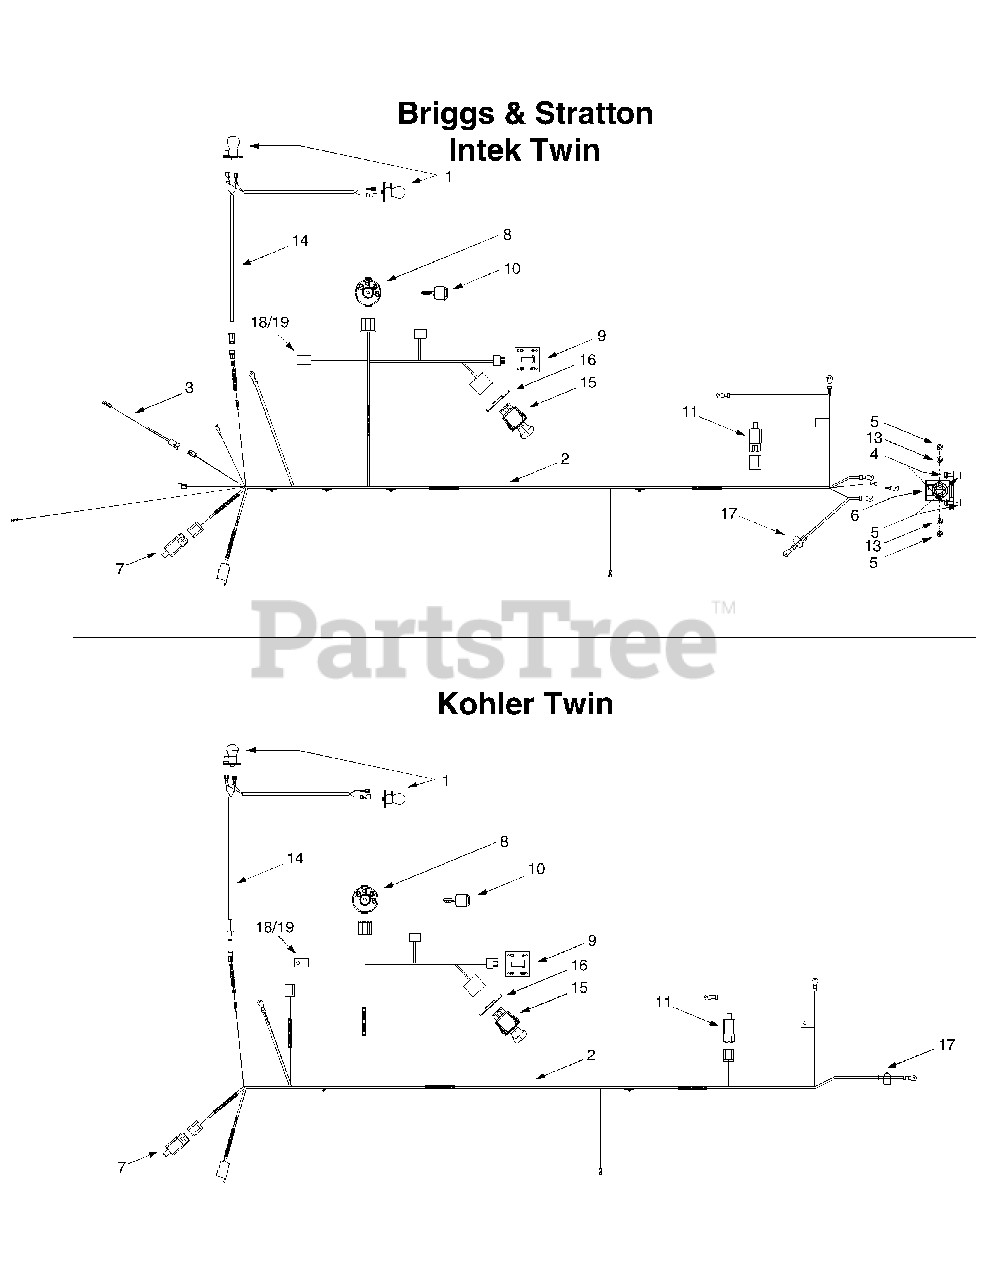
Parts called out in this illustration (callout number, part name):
1	Bulb/Socket Headlight Assembly
2	Wiring Harness w/o Ref. 14 (units w/ B&S Intek Twin)
2	Wiring Harness w/o Ref. 14 (units w/ Kohler Twin)
3	Harness Adapter, #18 x 5
4	Self Tapping Screw, 1/4-20 x .5
5	Hex Nut, 1/4-20
6	Solenoid, 12-volt, 100 Amp
7	Snap Mount Safety Interlock Switch (Brake)
8	Ignition Switch
9	Indicator Monitor / Hour Meter
10	Ignition Key
11	Safety Plunger Switch (Seat)
12	External Lock Washer, 1/4
13	Lock Washer, 1/4
14	Headlight Harness
15	Electric PTO Switch
16	Retainer Bracket
17	Positive Terminal Cover (Boot)
18	Fuse Holder
19	20-amp Fuse
